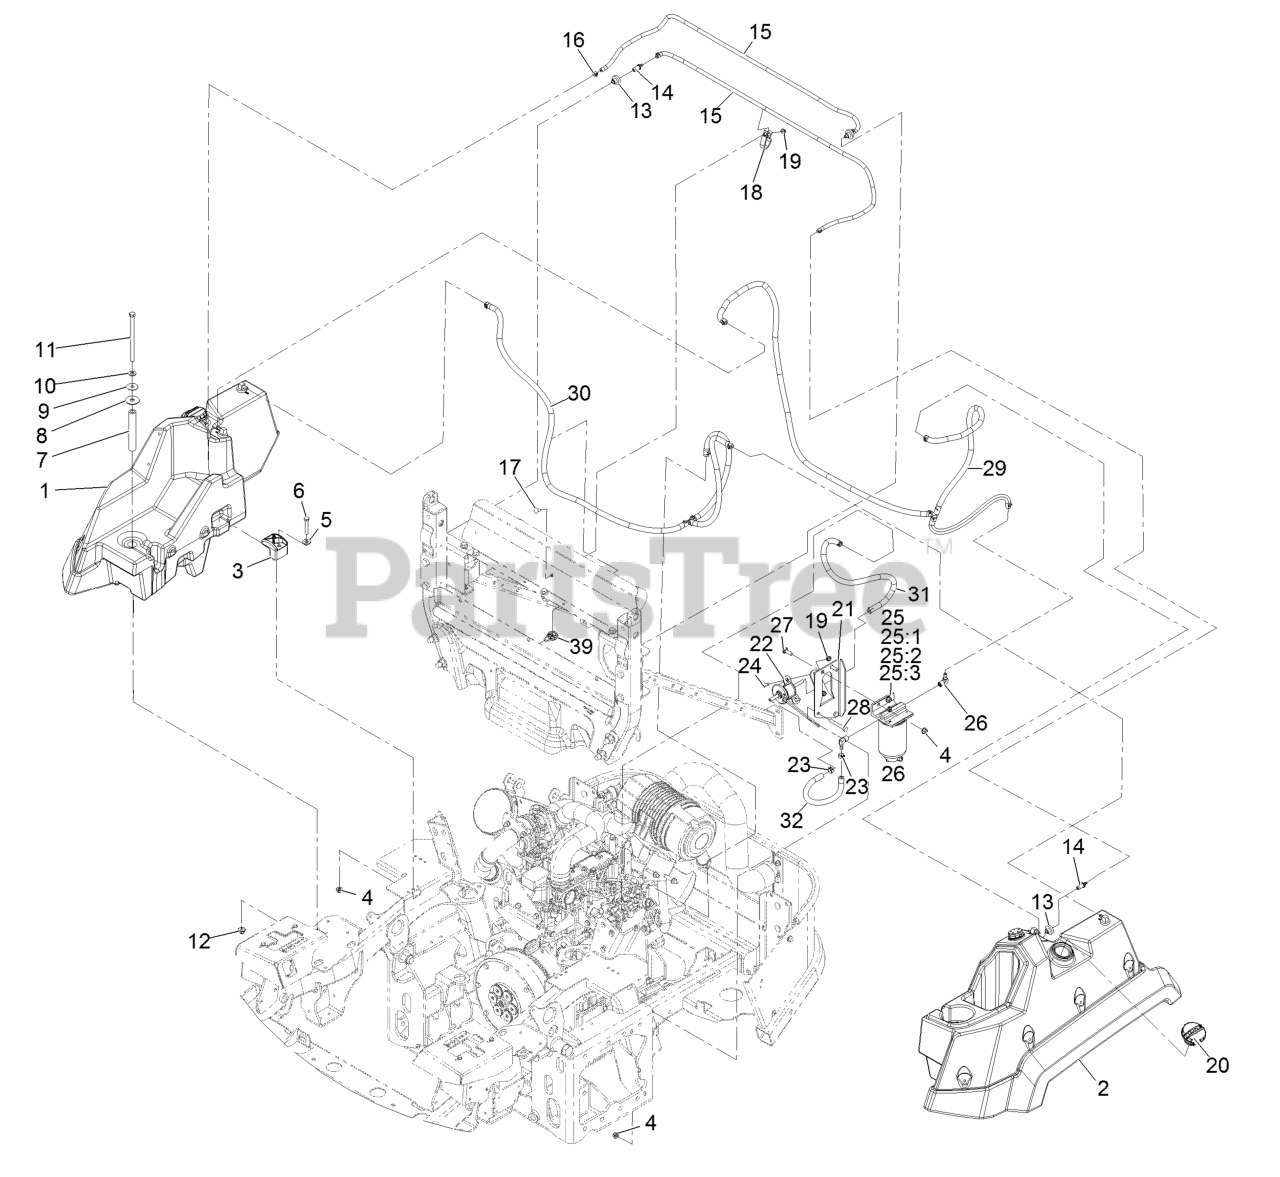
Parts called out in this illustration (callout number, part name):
1	RH Fuel Tank ASM
2	LH Fuel Tank ASM
4	Nut-Nyloc 5/16-18 Flg
5	Washer-5/16 Std
6	Screw-HH
7	Tube-Spacer
8	Washer-Rubber
9	Washer-Plain
10	Washer-3/8 SAE
11	Screw-HH
12	Nut-Nyloc 3/8-16 Flg
13	Bushing
14	Fitting-Orifice, Straight
15	Hose-Vent, Tank
16	Clamp-Hose
17	Bolt-Carriage 1/4-20 X 5/8
18	Clamp-Hose
19	Nut-Nyloc 1/4-20 Flg
20	Cap-Fuel, Diesel
21	Bracket-Filter & Pump, Fuel
22	Pump-Fuel, Electric
23	Clamp-Hose
24	Screw-Machine 1/4-20 X 3/4
25	Separator-Filter
25	ASM,Fuel Filter
25:1	Filter-Spin On
25:2	Filter,Fuel
25:3	Decal,Exmark Filter
26	Fitting-Elb, 90
27	Bolt-Carriage 5/16-18 X 1 Sp
28	Screw-HH 5/16-18 X 2 1/4
29	ASM-Fuel Line, Suction
30	ASM-Fuel Line, Return
31	Hose-Fuel
32	Hose-Fuel
39	Clip-Tie
